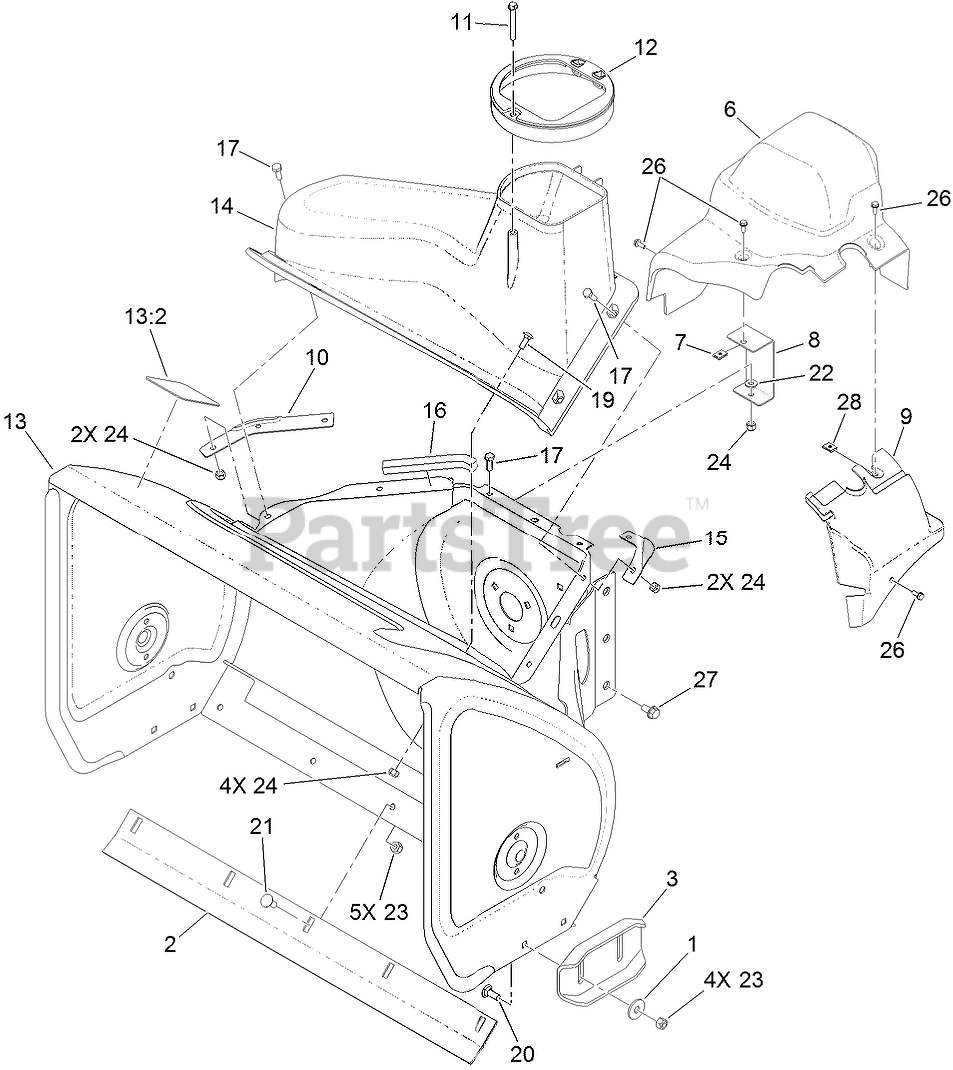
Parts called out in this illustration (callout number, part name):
1	WASHER
2	SCRAPER-FIXED
6	COVER-BELT
7	NUT-SPEED, U-TYPE
8	BRACKET-COVER, CLIP NUT
9	COVER-EXTENSION, BELT
10	SEAL-FLANGE, COVER
11	SCREW-PLASTITE
12	GUIDE-CHUTE
13	HOUSING-AUGER, 26 INCH
13:2	DECAL-DANGER, AUGER
16	SEAL-HOUSING
17	SCREW-HH
19	BOLT-CARR
20	SCREW-CARR
21	SCREW-CARR
22	WASHER-FLAT
23	NUT-LOCK, NI
24	NUT-LOCK, NI
26	SCREW-HWH
27	SCREW-HWHTF
28	NUT-SPEED
